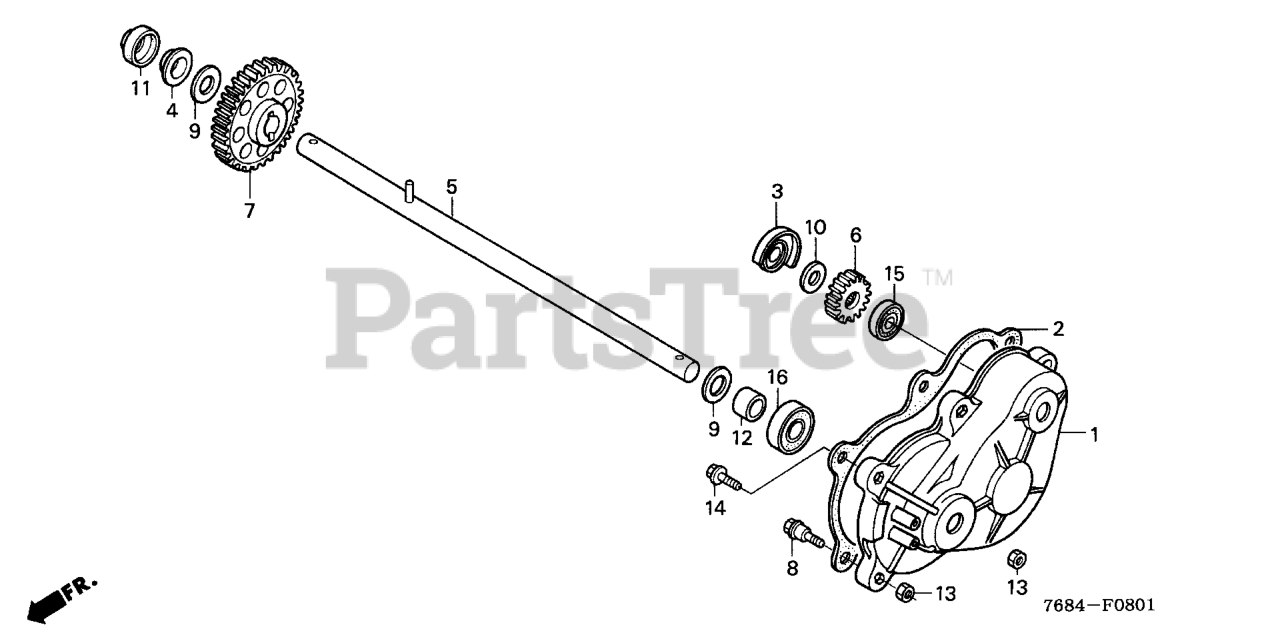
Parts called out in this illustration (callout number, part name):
1	CASE, R. TRANSMISSION
2	GASKET, TRANSMISSION CASE
3	BUSH, CROSS SHAFT
4	BUSH, FINAL SHAFT
5	SHAFT, WHEEL
6	GEAR, DRIVE (11T)
7	GEAR, DRIVEN (66T)
8	BOLT, TRANSMISSION SETTING
9	WASHER, DIFFERENTIAL GEAR
10	WASHER, THRUST (12X23X2)
11	DUST SEAL (20X34X7.5)
12	COLLAR, WHEEL SHAFT
13	NUT, HEX. (6MM)
14	BOLT, FLANGE (6X18)
15	BEARING, RADIAL BALL (6002UU)
16	BEARING, RADIAL BALL (6004UU)
